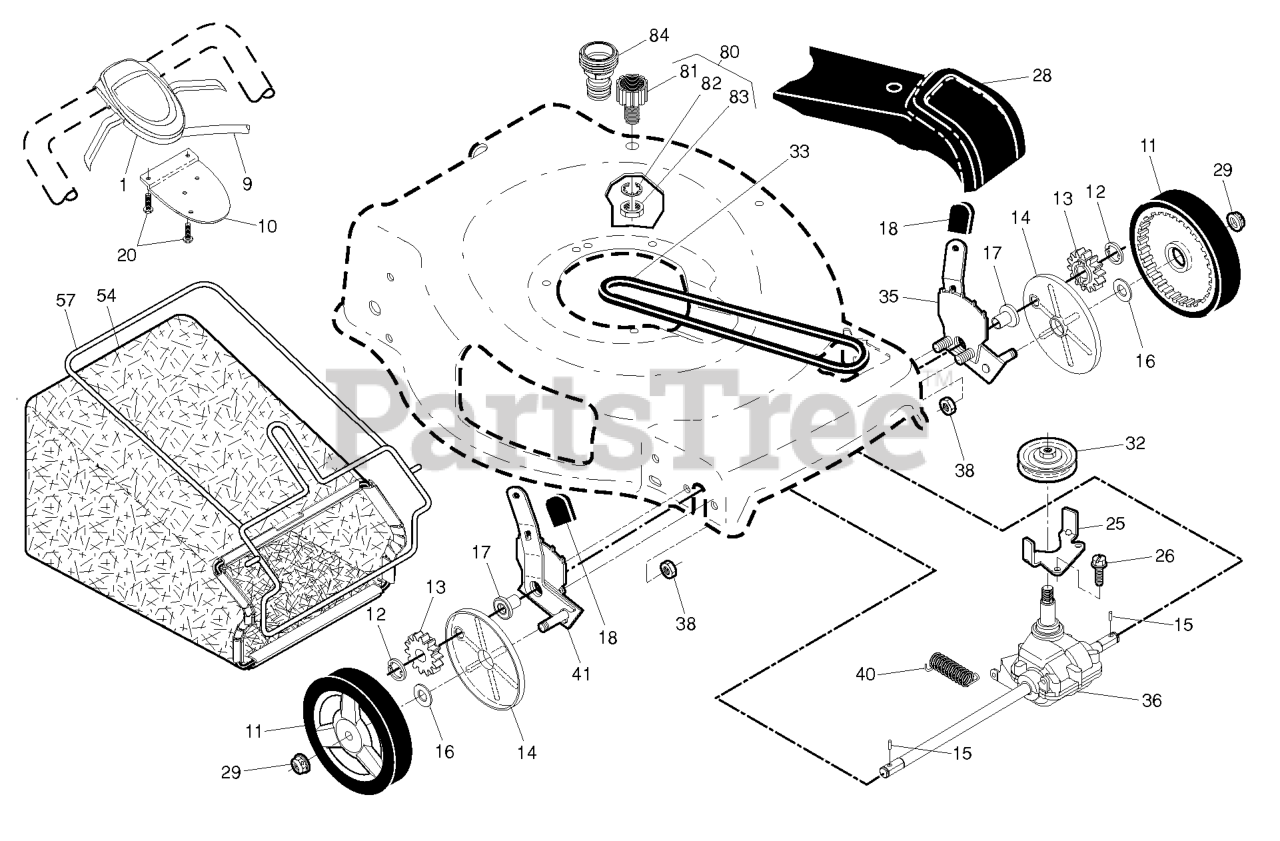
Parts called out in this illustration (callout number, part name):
1	CONTROL.AW2.22FGD.BS.GR/BK.E/F
9	CABLE.CONTROL.22FGD.GEN2
10	BRACKET.DRIVE.CONTR.GEN2.BLACK
11	WHEEL.8X1.75.H3SPK.RAD3.GY.BU3
12	E-RING 7/16 RE
13	PINION.14.TEETH.FGD
14	COVER.DUST.WHEEL
15	PAWL, DRIVE
16	WASHER FLUT
17	BEARING.ASM.
18	SELECTOR KNOB
20	SCREW, PHILLIPS HEAD 10 X 5/8
25	BRACKET.BELT.GUIDE.22+FGD.BZP
28	COVER.DRIVE.22.LABEL.HUSQVARNA
29	NUT.HEX.FLANGE.3/8-16.LO(3 2)
32	RP PULLEY.DRIVE.EZ/VAR.SCREWON
33	BELT.DRIVE.FWD.
35	ADJUSTER.ASM.9.22+/RF/LR.21/RF
36	TRANSMISSION.22PLUS.FGD.AW2/EZ
38	NUT.HEX.FLANGE.1/4
41	ADJUSTER.ASM.9.22+/RF/LR.21/LF
54	GBAG.A3610247T.SILV.HUSWT.BLUE
57	RB FRAME.GBAG.22PLUS
80	KIT.WASH-OUT.PORT.ZINC.WALK
81	WASHOUT.PORT.ZINC.RGD.22+
82	WASHER.LOCK.INTERNAL.TOOTH
83	LOCKNUT.HEX.WITH.O-RING
84	COUPLING.QUICK CONNECT
